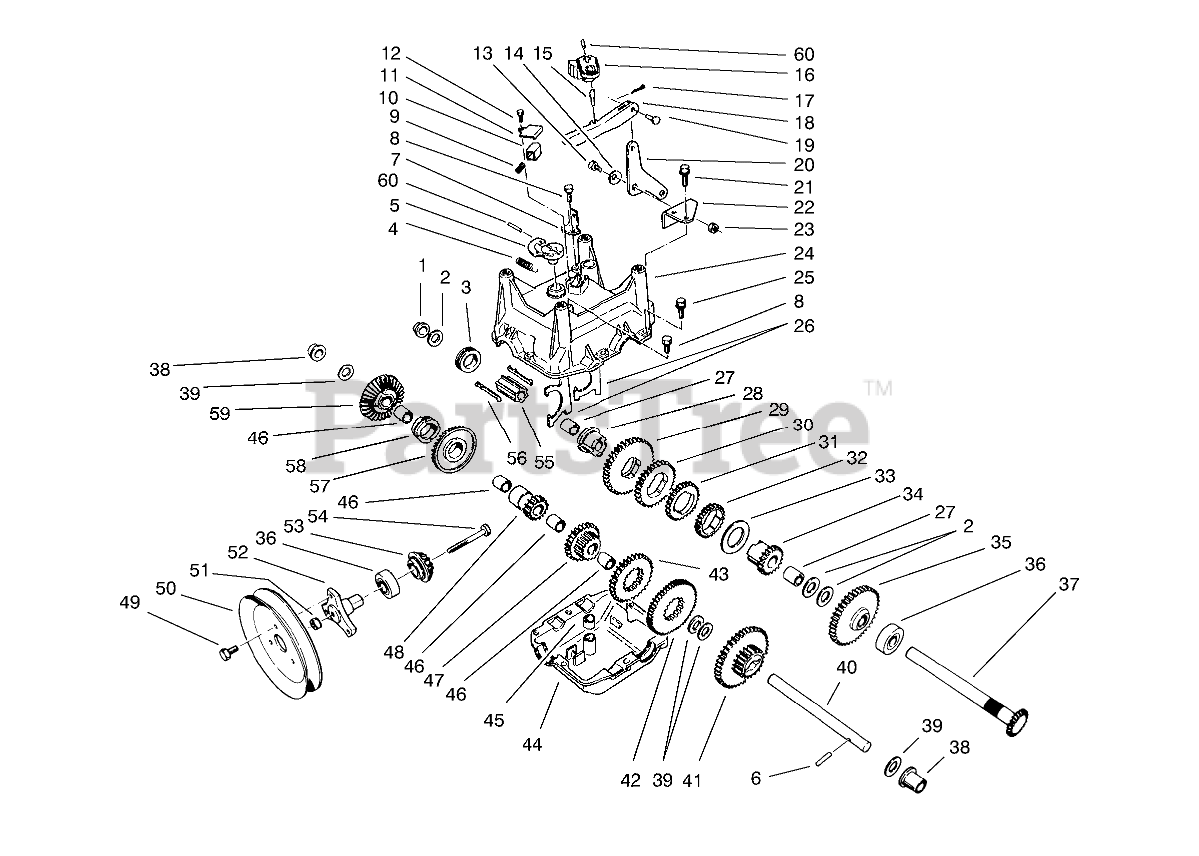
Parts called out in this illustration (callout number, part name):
1	BUSHING-FLANGE, OUTPUT
2	BEARING-THRUST
3	COLLAR-SHIFT
4	SPRING-EXTENSION
5	LEVER
6	PIN-SPRING
7	BRACKET-CABLE
8	SCREW-HWH
9	SPRING-DETENT
10	BUTTON-DETENT
11	COVER-DETENT
12	SCREW-HWH
13	SCREW-SHOULDER
14	WASHER-CURVED
15	PIN-LINK, GEAR SHIFT
16	LEVER-SHIFT, GEAR
17	PIN-COTTER
18	LINK-SHIFT, GEAR
19	PIN-CLEVIS
20	BELLCRANK
21	SCREW-HWH
22	BRACKET-BELLCRANK
23	NUT-LOCK, NI
24	GEARCASE-UPPER, CASING
25	SCREW-HWHTF
26	YOKE-SHIFT
27	BUSHING-OUTPUT
28	SLEEVE-GEAR
29	GEAR-45 T
30	GEAR-34 T
31	GEAR-27 T
32	GEAR-29 T
33	WASHER-THRUST
34	GEAR-SLEEVE, 19 T
35	GEAR-41 T
36	BEARING-BALL
37	SHAFT-OUTPUT
38	BUSHING-INTERMEDIATE
39	WASHER-THRUST
40	SHAFT-INTERMEDIATE
41	GEAR-19/41 T
42	GEAR-51 T
43	GEAR-33 T
44	GEARCASE-LOWER, CASING
45	BUSHING-YOKE
46	Bushing-Output
47	GEAR-26 T
48	GEAR-BEVEL, 15 T
49	SCREW
50	TRACTION-SHEAVE, HALF
51	NUT-HHF
52	HUB-PULLEY
53	PINION-BEVEL
54	SCREW-HH
55	SLEEVE-SHIFT
56	KEY-SHIFT
57	GEAR-BEVEL, 36 T
58	COLLAR-SHIFT
59	Gear-Bevel Reverse 36T (Incl. Ref. #46)
60	PIN-SPRING
